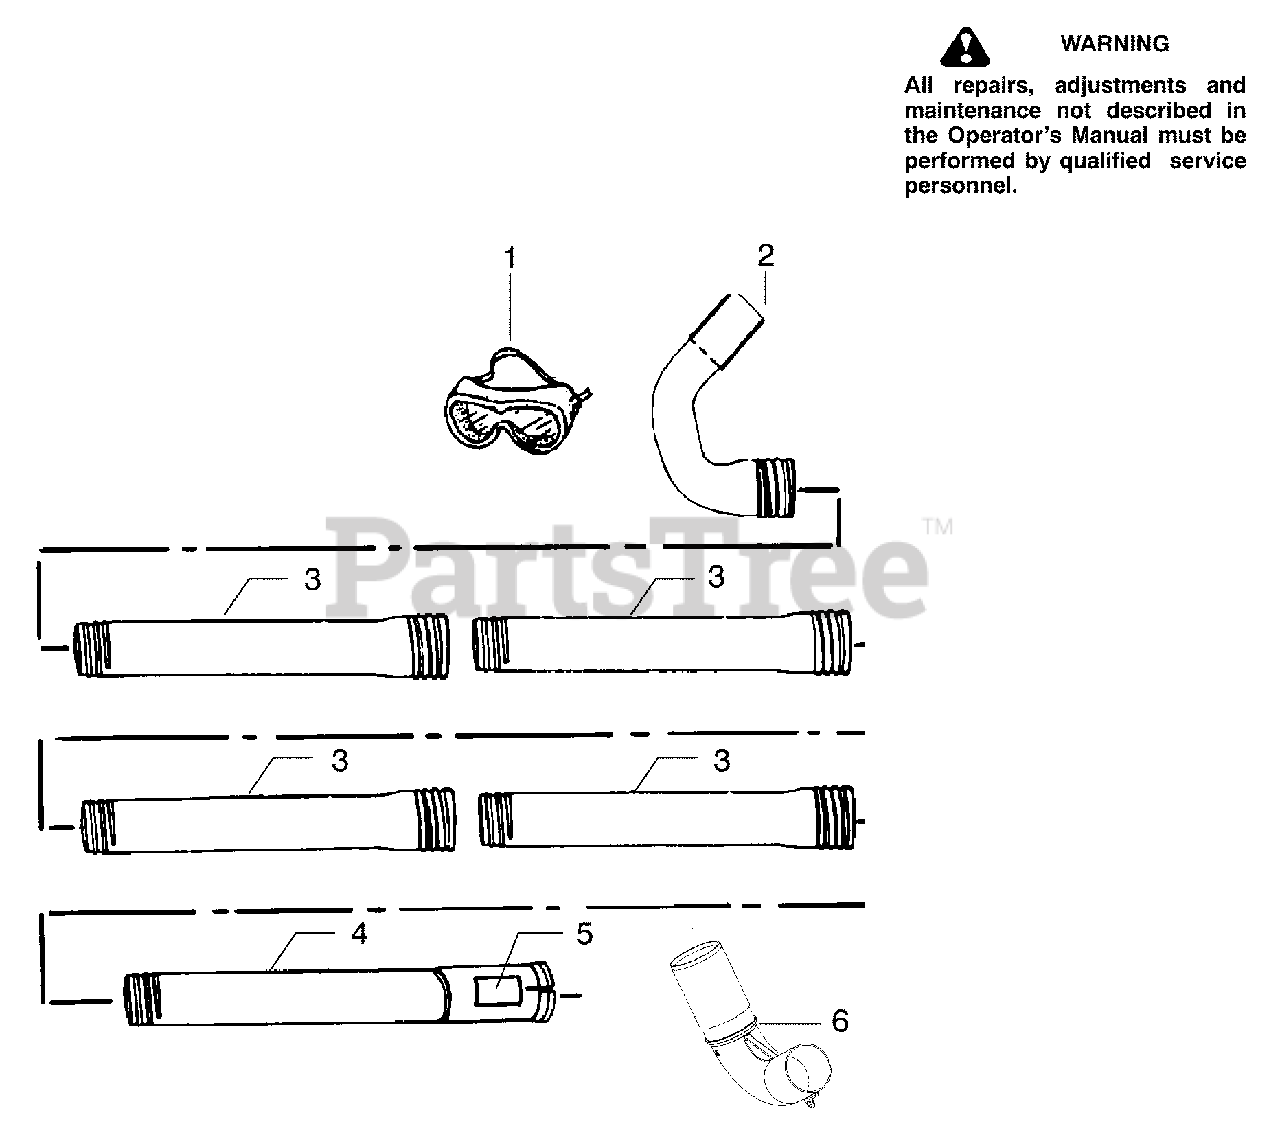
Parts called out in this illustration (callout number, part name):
4	Tube -- Pivot
5	Decal -- Warning
6	Tube -- Adapter
